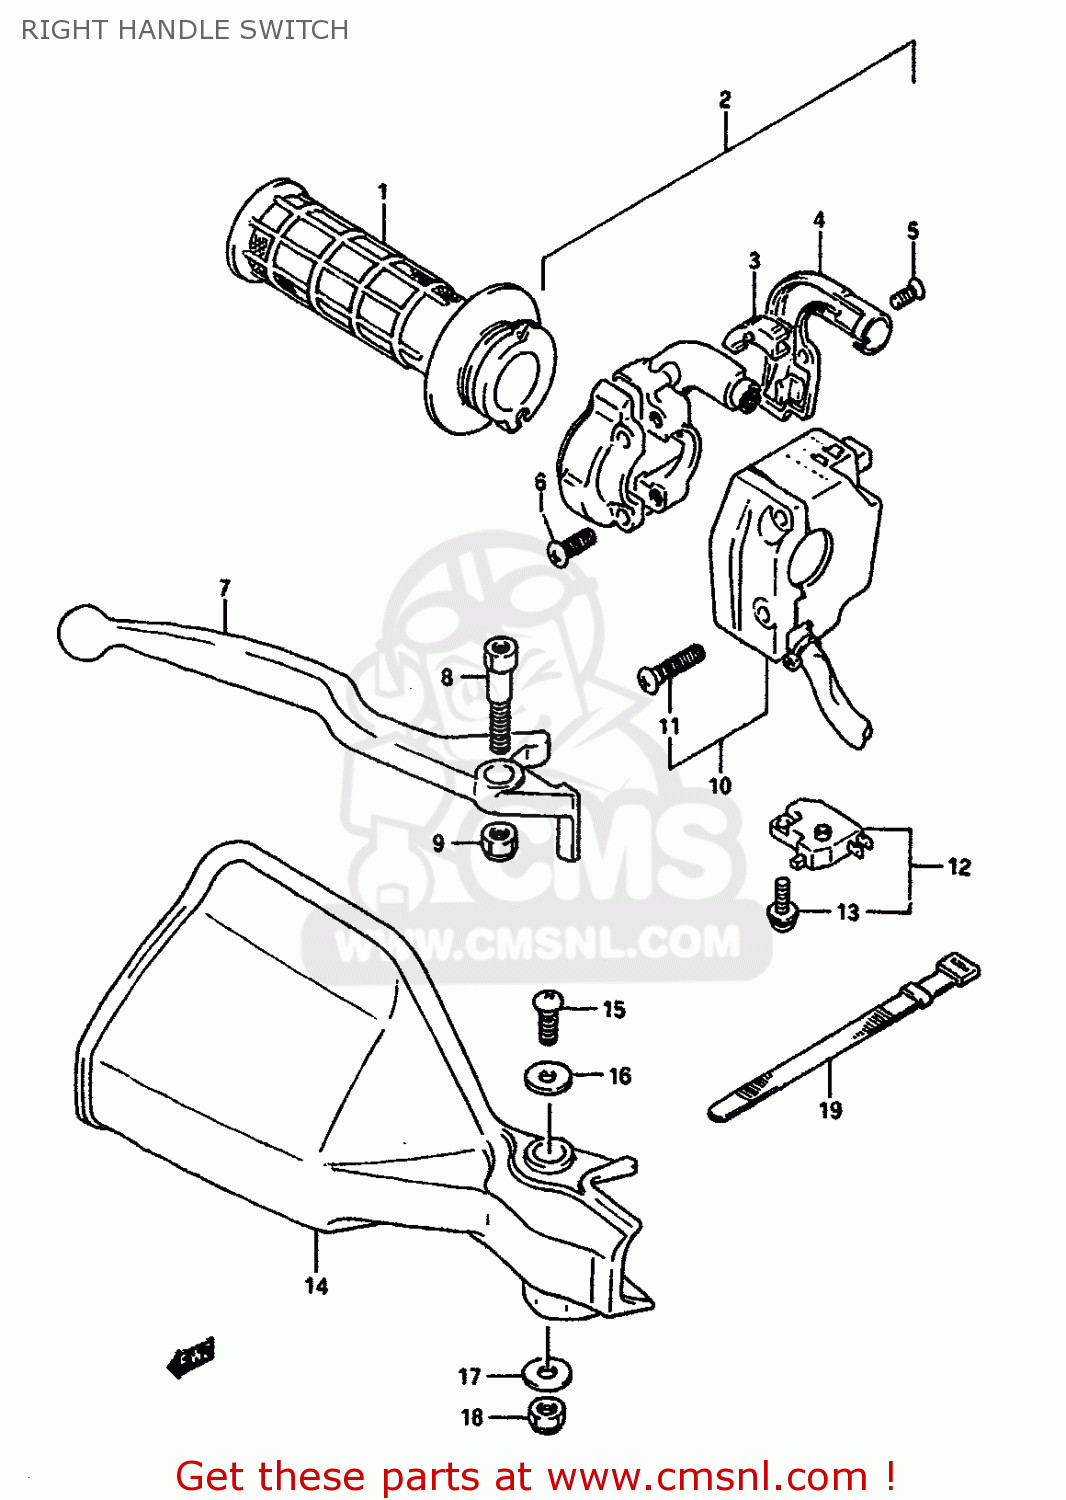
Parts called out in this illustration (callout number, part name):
1	GRIP,THROTTLE
2	CASE ASSEMBLY,THROTTLE
3	GUIDE PIECE,THROTTLE
4	COVER,THROTTLE CASE
5	SCREW 4X10
6	SCREW
7	LEVER,BRAKE
8	BOLT,BRAKE LEVER PIVOT
9	NUT 6MM
10	SWITCH ASSY,HANDLE RH
11	SCREW(5X25)
12	SWITCH ASSEMBLY,STOP
13	SCREW
14	COVER,KNUCKLE,R
15	SCREW(5X10)
16	WASHER (5.5X16X1.2)
17	WASHER (6.5X17X1.6)
18	NUT 6MM
19	CLAMP(L:120)
